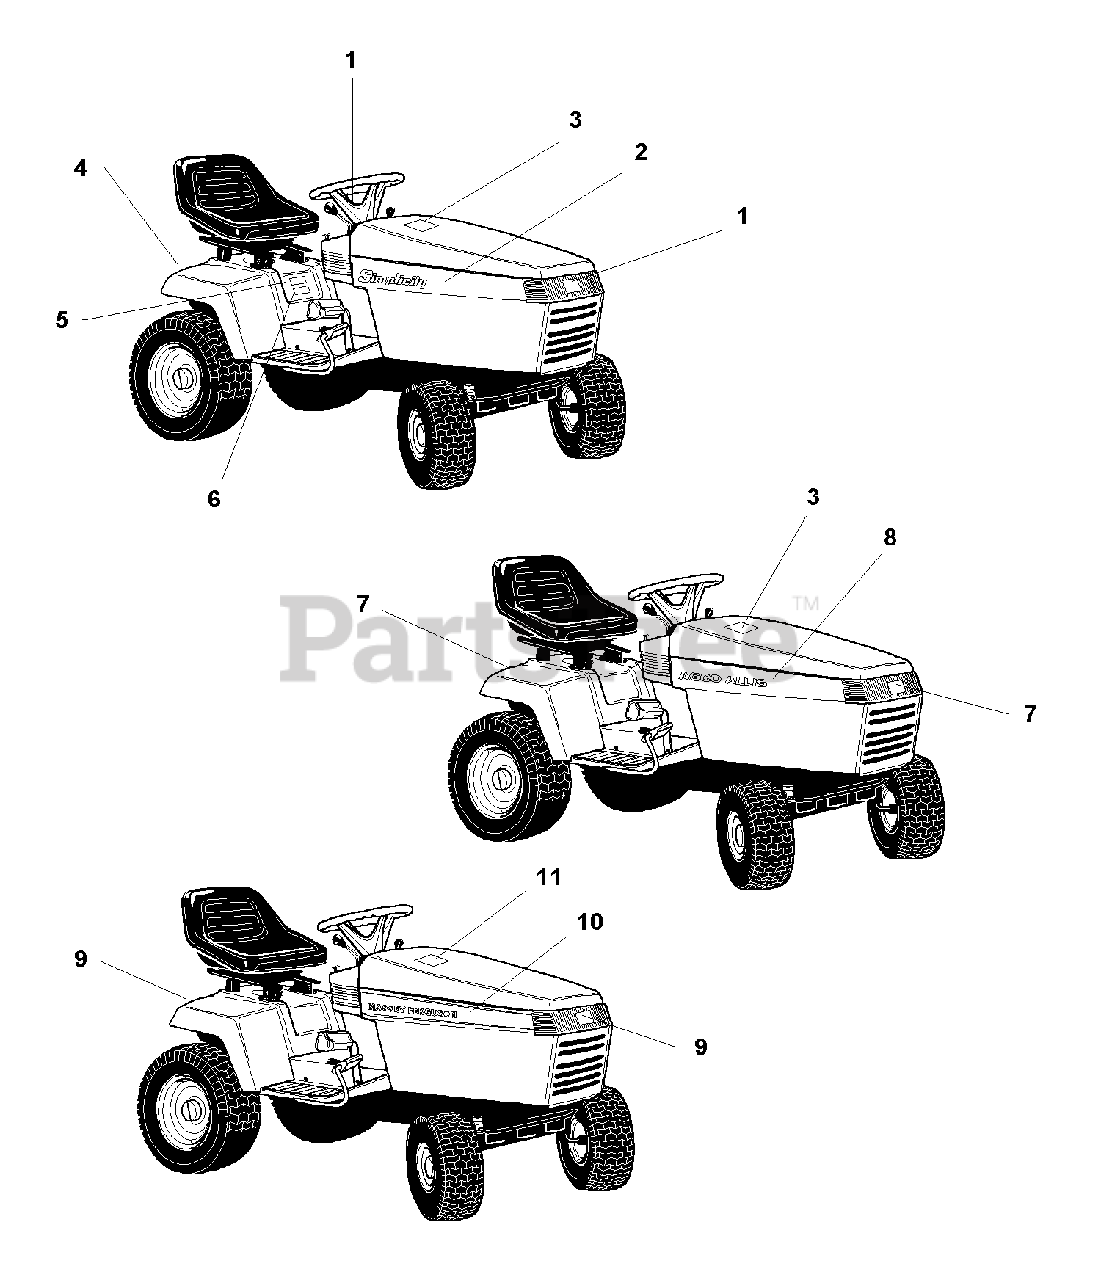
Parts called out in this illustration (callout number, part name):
1	DECAL, Simplicity Icon
2	DECAL, RH Hood, Simplicity
2	DECAL, LH Hood, Simplicity
3	DECAL, Paint, Simplicity & AGCO-Allis
4	DECAL, Simplicity Logo with Icon
5	DECAL, Seat Deck, Broadmoor, Simplicity
6	DECAL, Model, Simplicity Broadmoor - Hydro 17V-Twin
7	DECAL, AGCO-Allis Icon
8	DECAL, LH Hood - AGCO-Allis 1617HC Hydro
8	DECAL, RH Hood - AGCO-Allis 1617HC Hydro
8	DECAL, LH Hood - AGCO
8	DECAL, RH Hood - AGCO
9	DECAL, Massey Ferguson Icon
10	DECAL, LH Hood, Massey Ferguson 2617HC Hydro
10	DECAL, RH Hood, Massey Ferguson 2617HC Hydro
11	DECAL, Paint, Massey Ferguson
